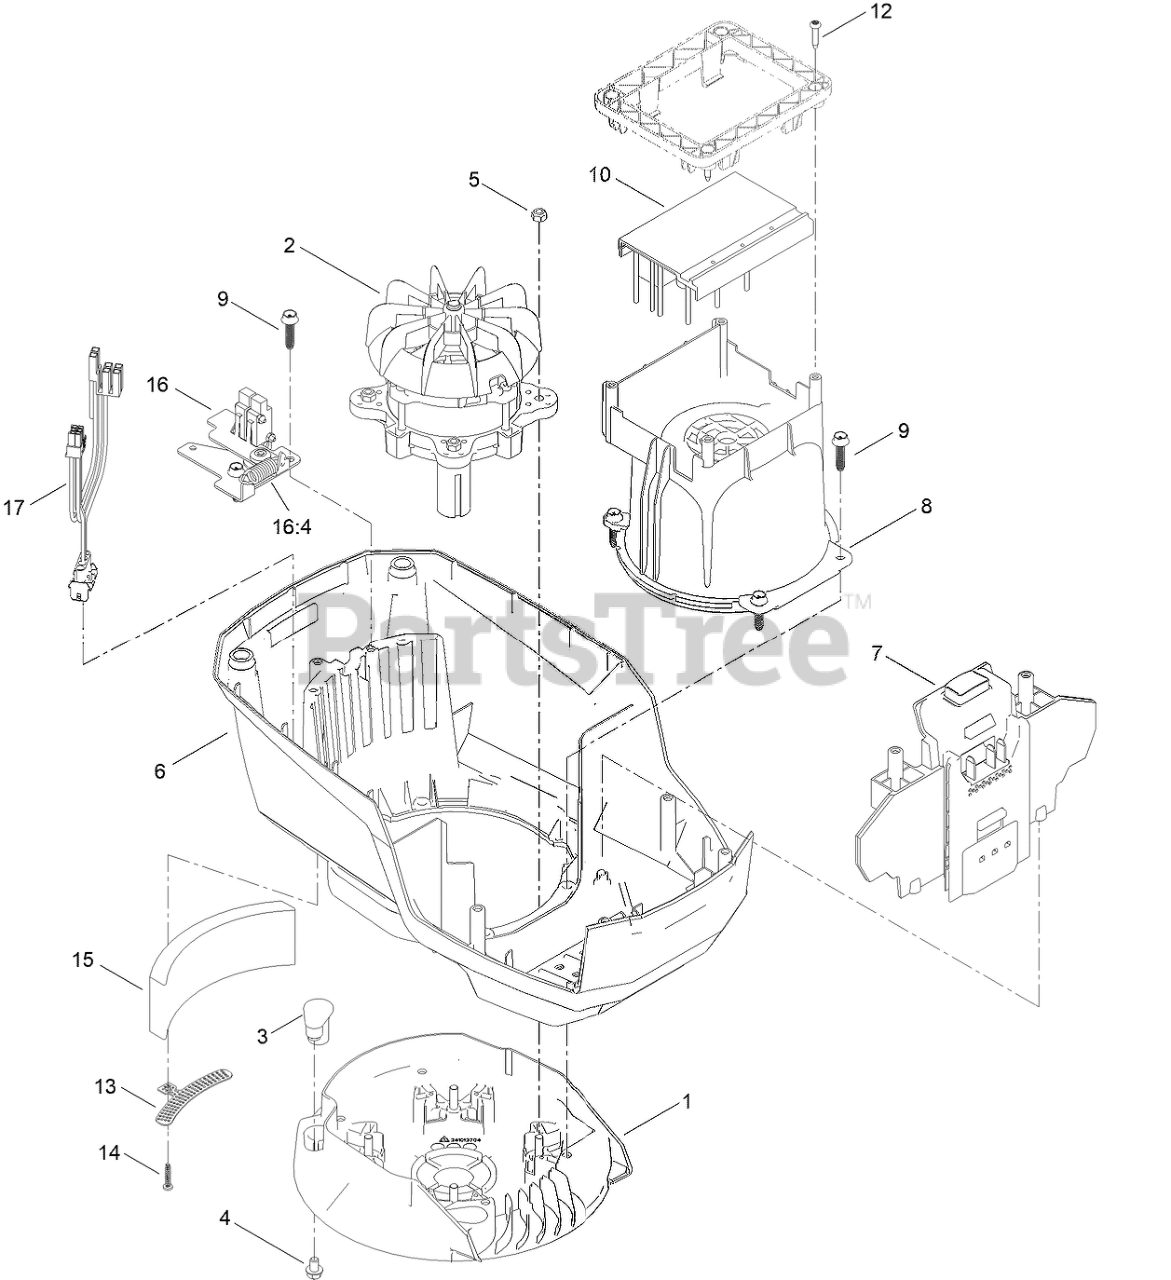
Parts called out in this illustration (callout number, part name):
1	BASE-MOUNT, MOTOR
2	MOTOR, 60 VOLT
3	INSERT-MOUNT, Motor
5	NUT-LOCK
6	SHROUD-LOWER
7	BATTERY RECIEVER ASM
8	SHROUD-MOTOR
9	SCREW-FLANGE, PLASTIC
10	CONTROLLER-MOTOR, 60V [2-SP]
13	BRACKET-FOAM
14	SCREW-PLASTIC, PPH
16	BAIL SWITCH ASM
16:4	SPRING-EXTENSION
17	HARNESS-WIRE
